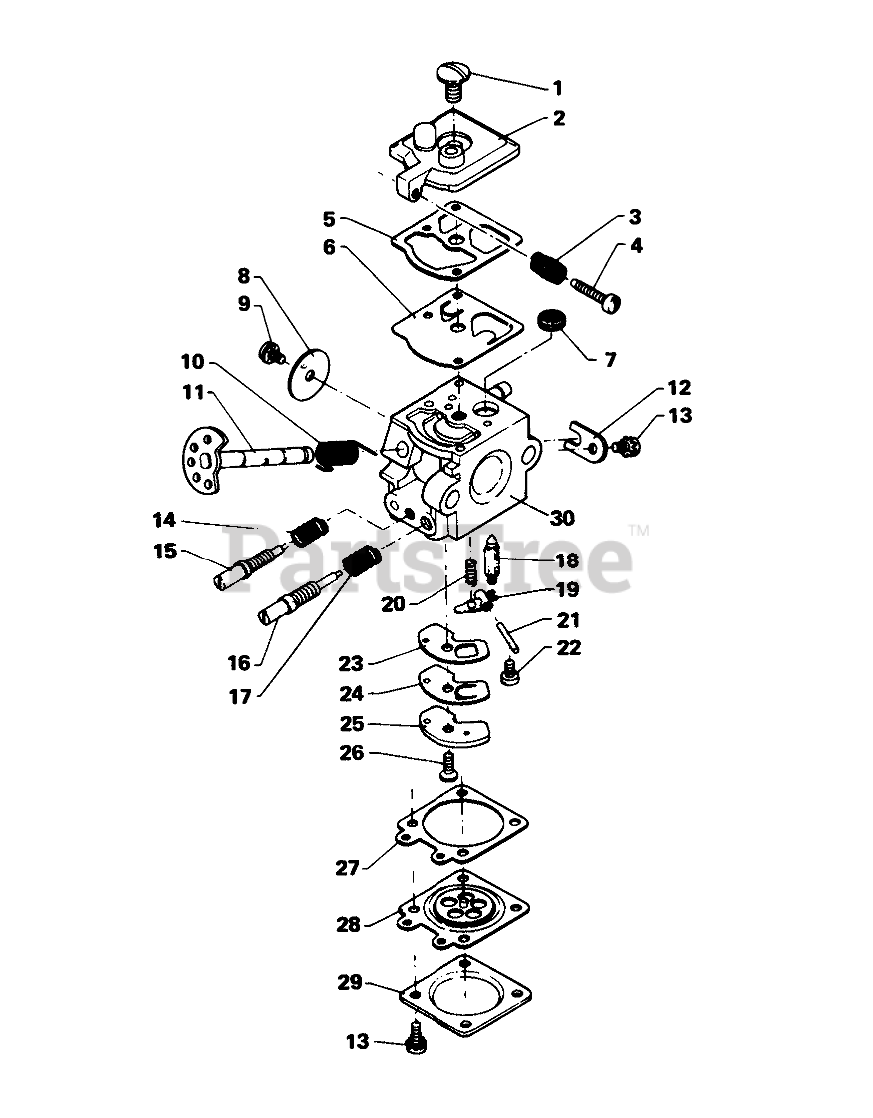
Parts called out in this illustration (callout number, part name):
1	Screw
2	Cover, Fuel Pump
3	Spring, Idle Screw
4	Screw, Idle Adjustment
5	PUMP GASKET
6	Diaphragm Fuel Pump
7	Screen Inlet
8	Valve, Throttle
9	Screw
10	Spring-Throttle Lever
11	Shaft, Throttle
12	Clip Throttle Shaft
13	Screw
14	Spring, Needle
15	Needle, Idle
16	Needle, High Speed
17	Spring, HS Needle
18	INLET NEEDLE VALVE
19	Lever Metering
20	Spring, Lever
21	Metering Lever Pin
22	Screw-Metering Pin
23	Gasket-Circuit Plate
24	Diaphragm Circuit Plate
25	Plate, Circuit
26	Screw-Circuit Plate
27	Gasket, Diaphragm
28	METERING DIAPHRAGM
29	Cover, Diaphragm
30	Short Block
